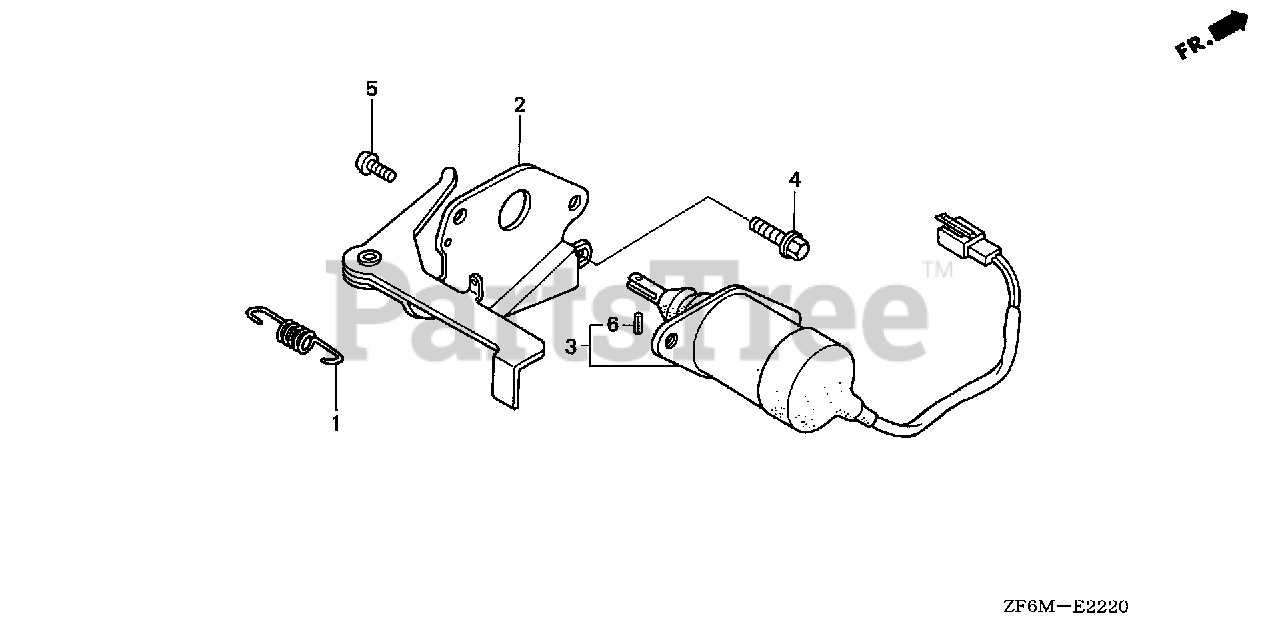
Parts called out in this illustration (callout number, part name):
1	SPRING, CHOKE RETURN
2	LEVER, THROTTLE
3	SOLENOID ASSY.
4	BOLT, FLANGE (6X12) (CT200)
5	SCREW, PAN (5X8)
6	PIN, SPRING (2.5X16)
